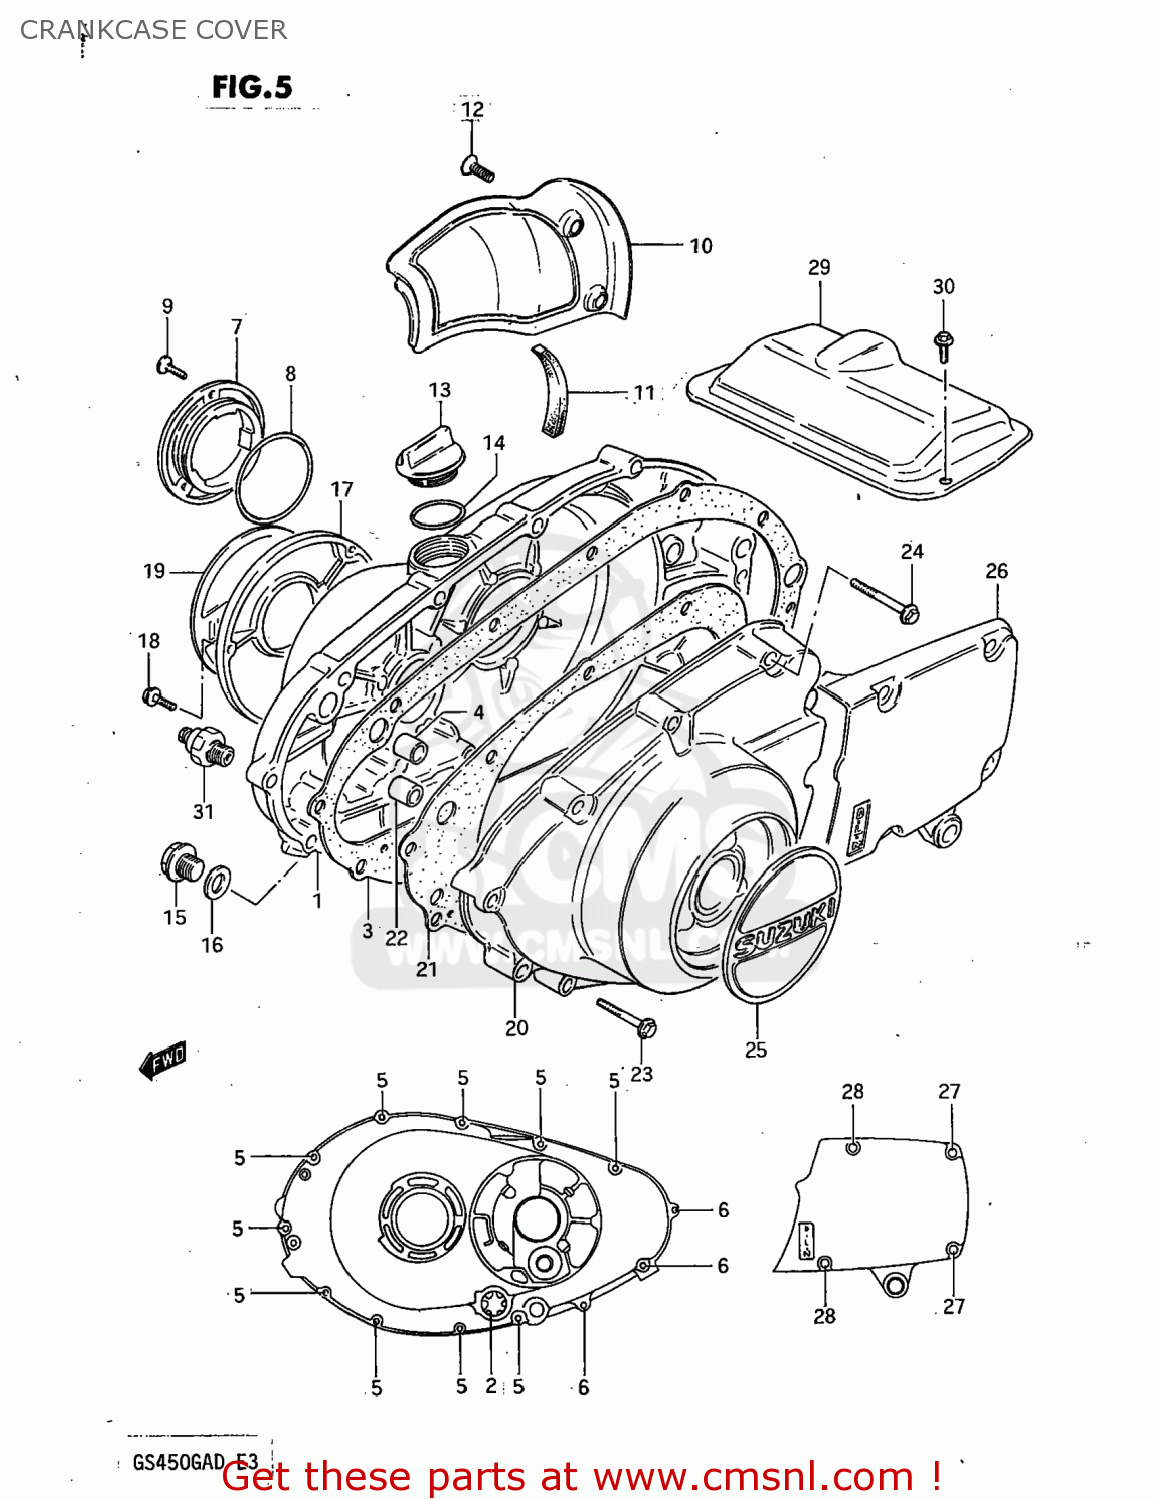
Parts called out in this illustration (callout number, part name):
1	COVER,CLUTCH
2	LENS,OIL LEVEL CHECK
3	GASKET,CLUTCH COVER (MCA)
4	PIN
5	BOLT (6X35)
6	BOLT
7	CAP,CARBURETOR INSPECTION
8	O RING(D:2.4,ID:52.6)
9	SCREW
11	GUARD,BELT COOLING DUCT,CENTER
12	SCREW
13	PLUG
14	O-RING
15	PLUG (14X12)
16	GASKET(14X19.2X2) (NAS)
17	COVER,CONTACT BREAKER
18	BOLT 5X16
19	EMBLEM,MAGNETO COVER
20	COVER
21	GASKET,MAGNETO COVER (A
22	PIN
23	BOLT
24	BOLT (6X30)
25	EMBLEM,MAGNETO COVER
26	COVER,SPROCKET
27	BOLT (6X20)
28	BOLT
29	COVER,STARTER MOTOR
30	BOLT
31	SWITCH ASSEMBLY
